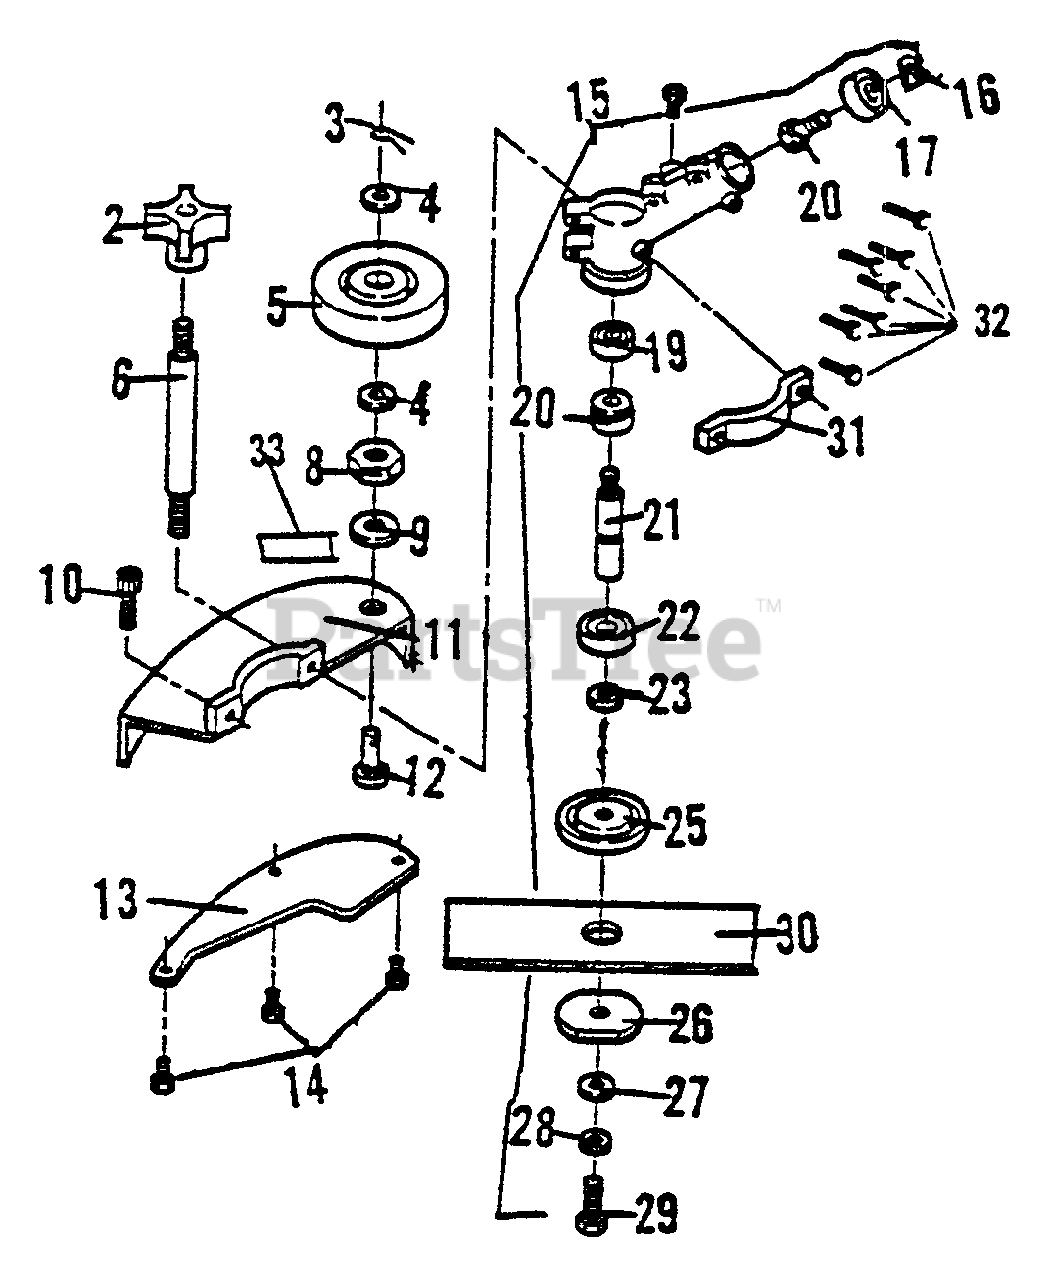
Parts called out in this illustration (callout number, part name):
2	KNOB
3	PIN, SPLIT
5	WHEEL, POLY
6	HANDLE, SHAFT
10	SCREW
11	EDGER GUARD
13	EDGER SHIELD
14	SCREW
15	GEAR CASE ASSY
16	RING, RETAINING
17	BEARING, BALL
19	BEARING, BALL
20	GEAR SET
21	GEAR - SHAFT
22	BEARING, BALL
23	SHAFT, SPACER
25	HOLDER - A
26	HOLDER B
27	WASHER
28	WASHER
30	BLADE, EDGER
31	BRACKET, EDGER GUARD
32	SCREW
33	LABEL - CAUTION
